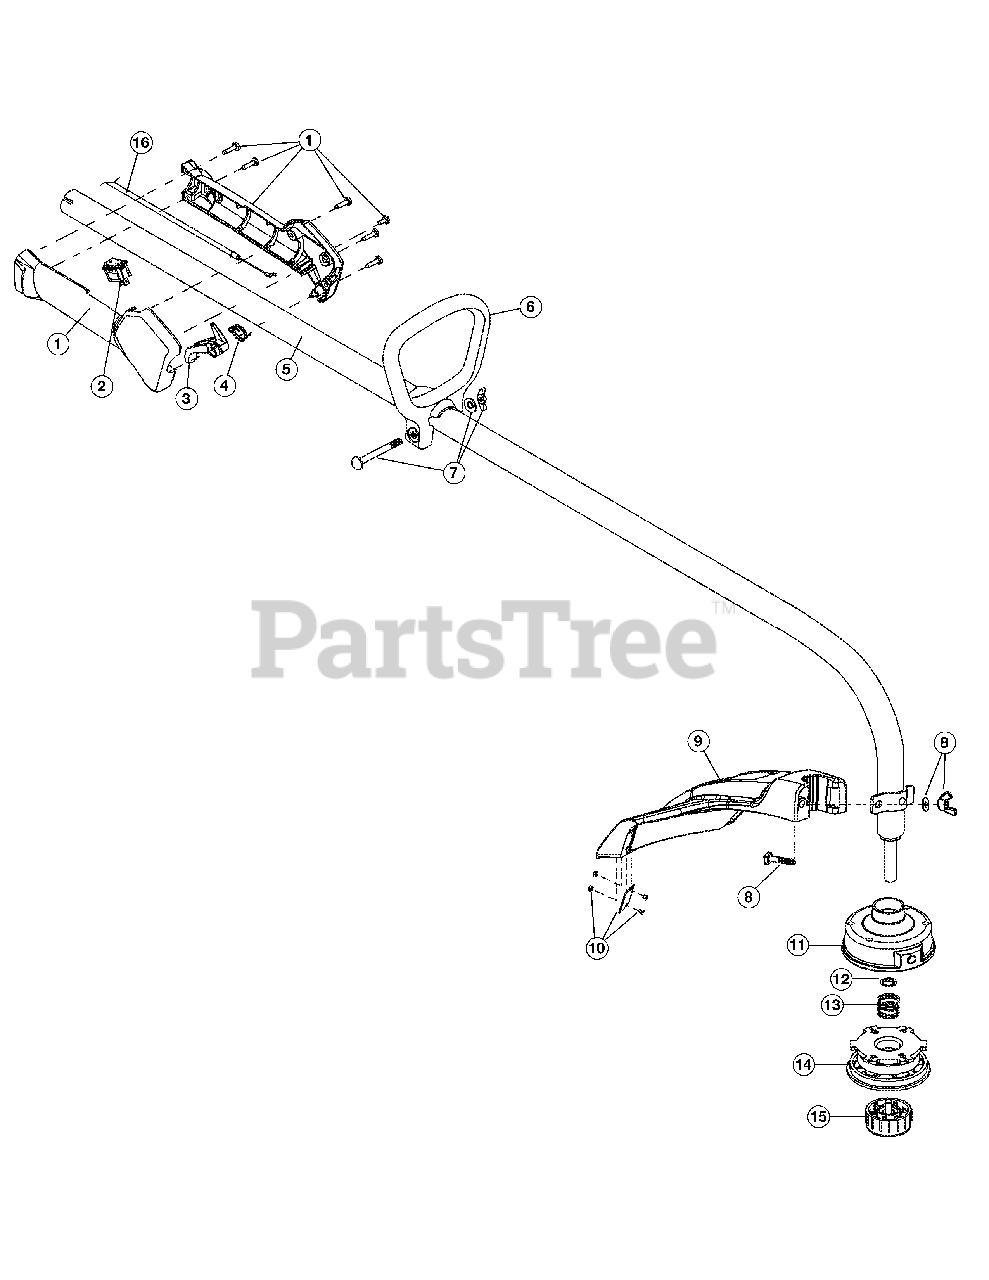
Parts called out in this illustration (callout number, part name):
1	Throttle Housing Assembly (Incl. Ref No. 2-4)
3	Throttle Trigger
4	Throttle Trigger Spring
5	Drive Shaft Housing Assembly
6	D-Handle (Incl. Ref No. 7)
7	Handle Hardware
8	Guard Mounting Hardware
9	Guard (Incl. Ref No. 10)
10	Blade Assembly
11	Outer Spool Assembly (Incl. Ref No. 12)
14	Inner Reel
15	Bump Head Knob Assembly
16	Throttle Cable
